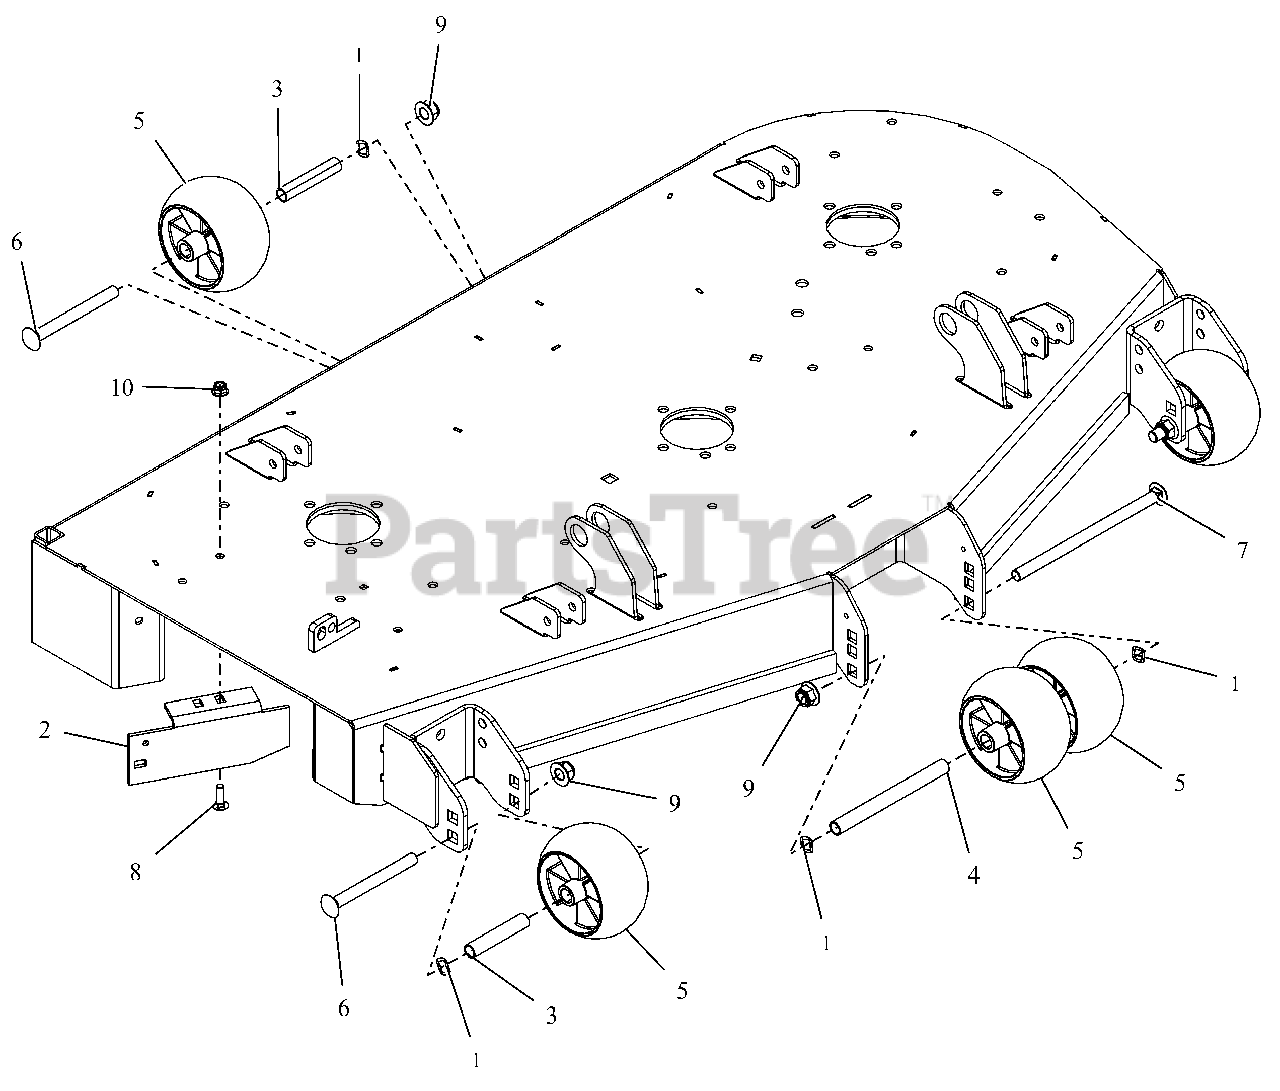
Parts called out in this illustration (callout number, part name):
1	WAVE WASHER .531X.781X.125FH
2	44"-48" SIDE DISCH BAFFLE -RED
3	SPACER, .510X.625X3.35
4	SPACER, .510X.625X6.50
5	ANTI-SCALP WHEEL - 5X3 CTR
6	BLT-RDHDSQNK .50-13X5.00 GR5YZ
7	@BLT-RDHDSQNK .50-13X8.50 G5YZ
8	@BLT-RDHDSQNK .31-18X1.00 G5YZ
9	@NUT-LK-NYL-FLG .50-13 YWZC
10	@NUT-LK-NYL-FLG .31-18 YWZC
